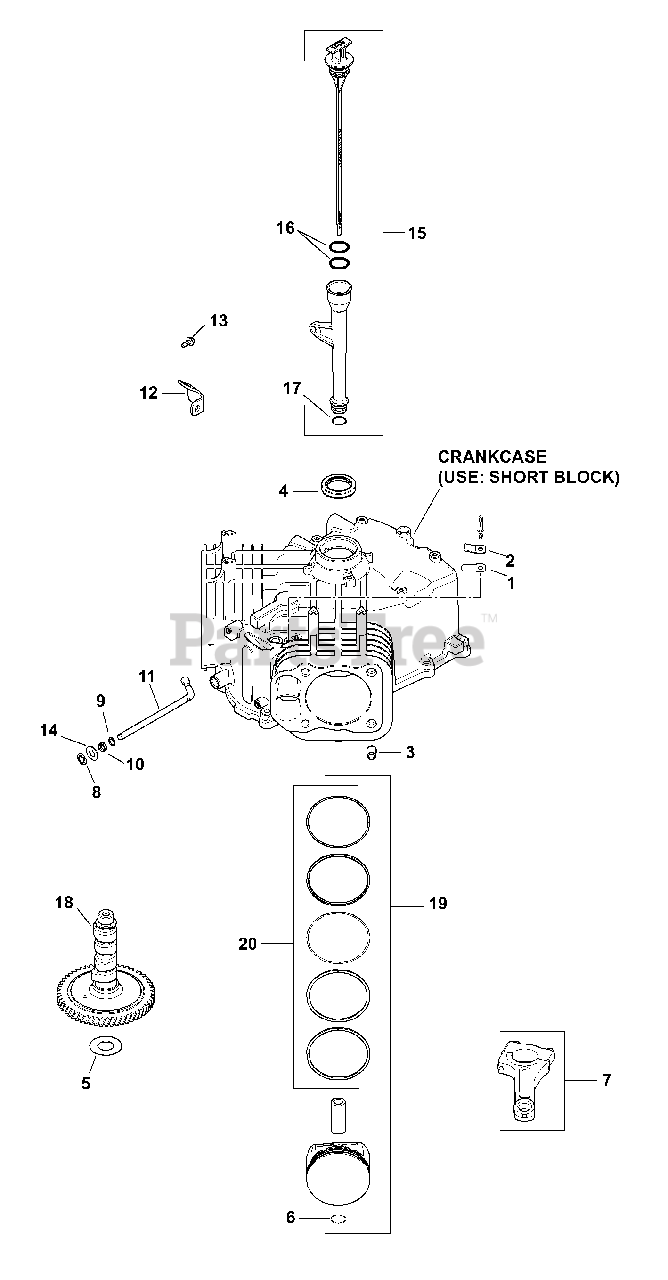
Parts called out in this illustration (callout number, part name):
1	Breather Reed
2	Breather Reed Retainer
4	Oil Seal (Helix Lip)
5	Camshaft Shim (White .028")
5	Camshaft Shim (Blue .03")
5	Camshaft Shim (Red .032")
5	Camshaft Shim (Yellow .034")
5	Camshaft Shim (Green .036")
5	Camshaft Shim (Gray .038")
5	Camshaft Shim (Black .04")
6	Piston Pin Retainer
7	Connecting Rod (Std)
8	Ring Retainer
9	Flat Washer, 11/32
10	Governor Cross Shaft Seal
11	Governor Cross Shaft
12	Oil Fill Tube Bracket
13	Flg. Thd. Frm. Screw, M5 x 0.8 x 13
14	Flat Washer, 9mm
15	Dipstick And Tube Kit
16	Dipstick O-Ring
17	O-Ring, Lower Oil Fill Tube
18	Camshaft Assembly
19	Piston w/ Ring Kit (Std)
19	Piston W/ Ring Kit (0.25) 83mm
19	Piston W/ Ring Kit (0.08) 83mm
20	Piston Ring Set, (Std)
20	Ring Set (.08)
20	Ring Set (.25)
